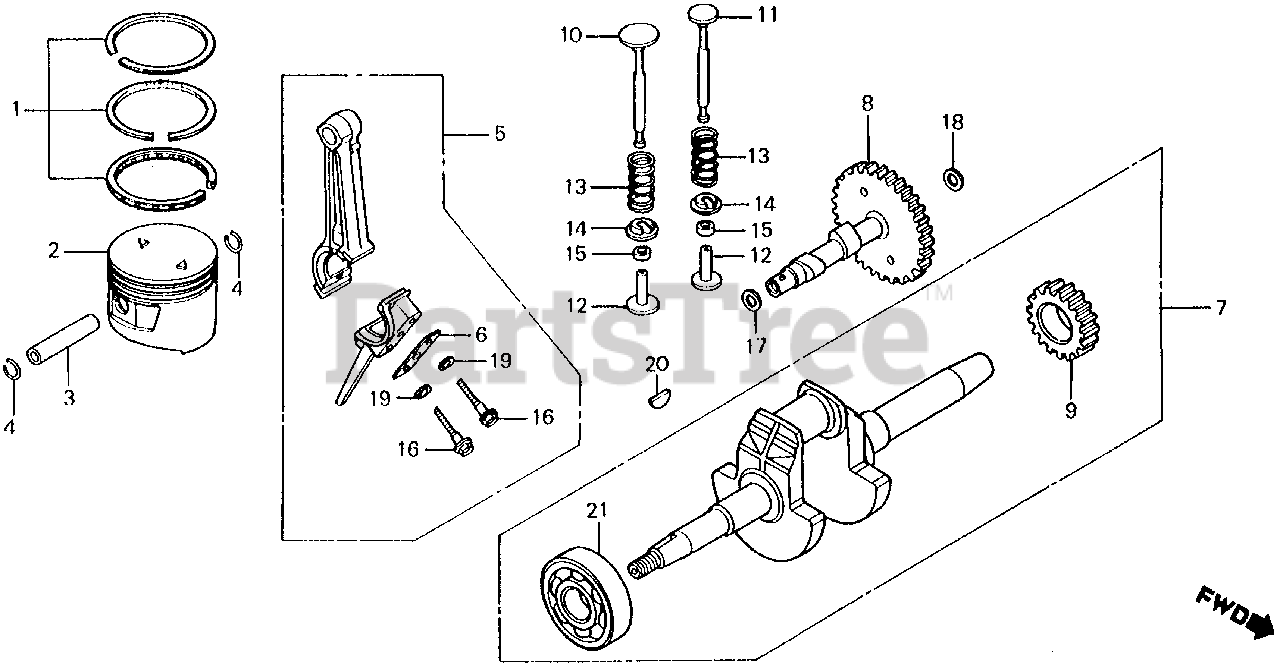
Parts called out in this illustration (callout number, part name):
1	RING SET, PISTON (STD)
1	RING SET, PISTON (OS 0.25)
1	RING SET, PISTON (OS 0.50)
1	RING SET, PISTON (0.75)
2	PISTON
2	PISTON (STD)
2	PISTON (OS 0.25)
2	PISTON (OS 0.50)
2	PISTON (0.75)
3	PIN, PISTON
4	CLIP, PISTON PIN (10MM)
5	ROD ASSY., CONNECTING
6	WASHER, CONNECTING ROD (NOT AVAILABLE)
7	CRANKSHAFT
8	CAMSHAFT (NOT AVAILABLE)
9	GEAR, TIMING
10	VALVE, IN.
11	VALVE, EX.
12	LIFTER, VALVE
13	SPRING, VALVE
14	RETAINER, VALVE SPRING
15	ADJUSTER, TAPPET CLEARANCE
16	BOLT, CONNECTING ROD
17	WASHER (10MM)
18	WASHER, THRUST (9.9MM)
19	WASHER, LOCK
20	KEY, WOODRUFF (3MM)
21	BEARING, RADIAL BALL (6203)
